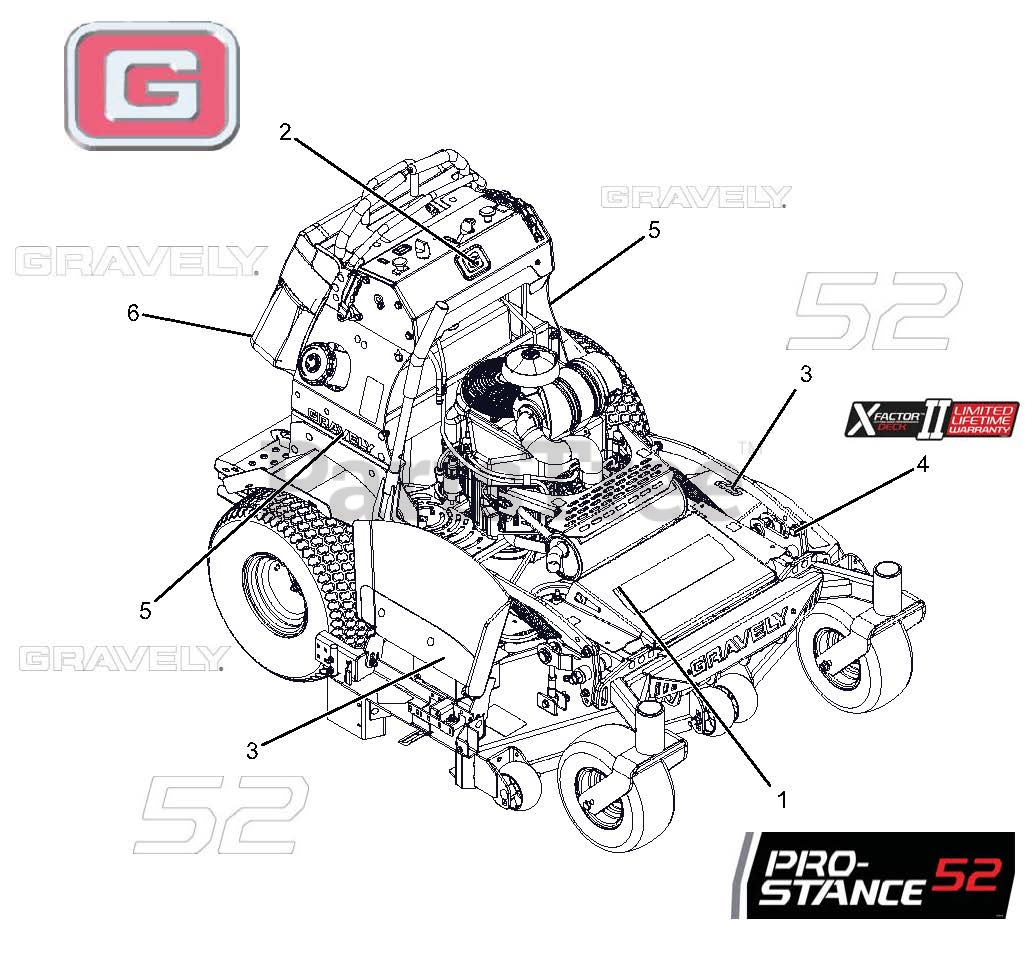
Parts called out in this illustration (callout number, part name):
1	DECAL, PROSTANCE 52
2	DECAL, GRAVELY BRAND
3	DECAL, 52"
4	DECAL, X-FACTOR DECK
5	DECAL, 9.5" GRAVELY LOGO
6	DECAL, 13.5" GRAVELY LOGO
